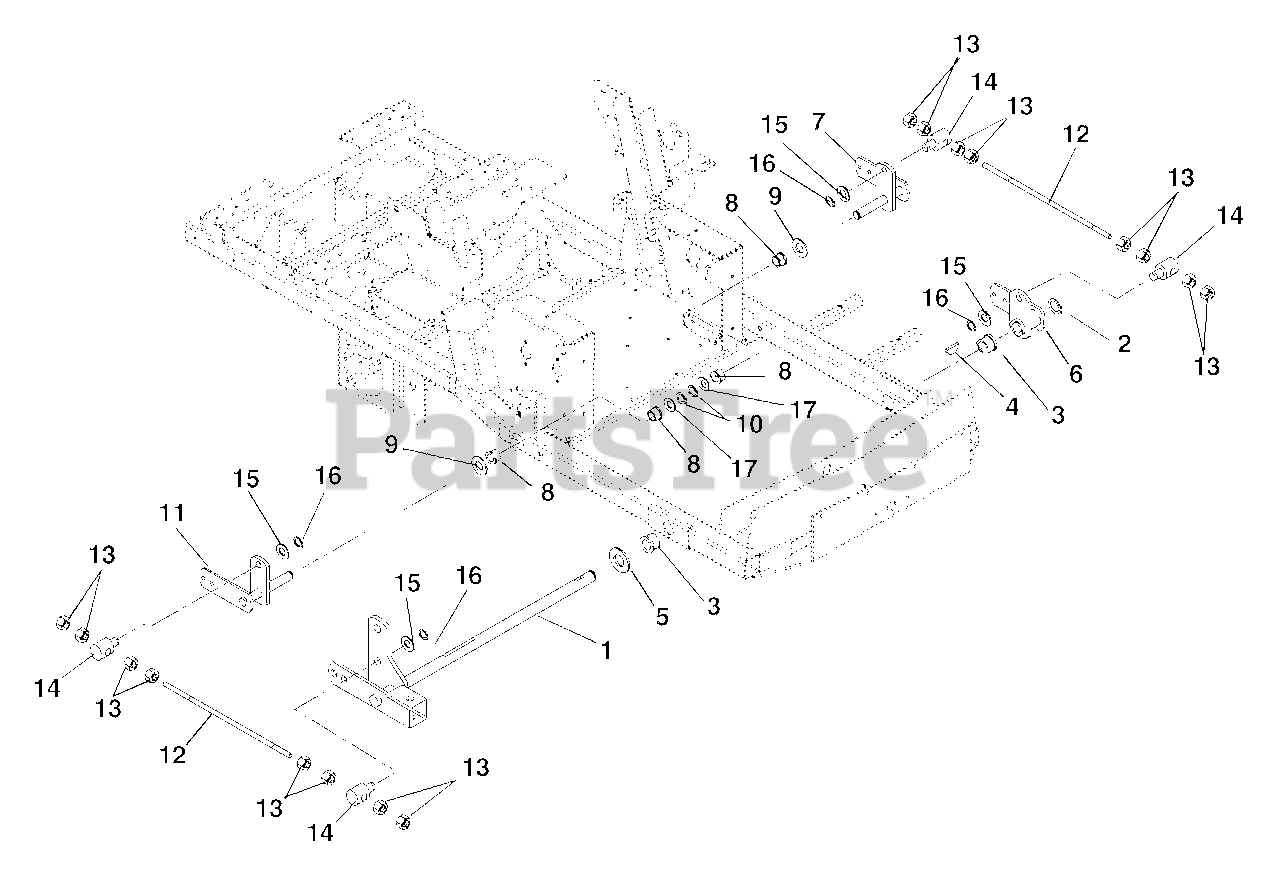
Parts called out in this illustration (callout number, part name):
1	MOWER LIFT
2	RG-RTNG-EXT 1.00X.078
3	BSHG-FLG1.020X1.385X.75X1.75NY
4	KEY-WDRF .25X1.00 HRD #15
5	WSHR-FL-STL 1.063X2.00X.134
6	WMT, FRONT MOWER LIFT-LH
7	WMT, REAR LIFT ARM -LH
8	BSHG-FLG .762X1.0X.580X1.48 NY
9	WSHR-HDND-THRST .758X1.23X.031
10	RG-RTNG-EXT .689X.078
11	WMT, REAR LIFT ARM - RH
12	ROD, LIFT ASSIST
13	NUT-JAM .50-13 YWZC
14	PIVOT, MWR LIFT
15	WSHR-FL-STL .630X1.005X.062 YZ
16	RG-RTNG-EXT .625X.050
17	WSHR-FL-STL .755X1.25X.125 YZ
